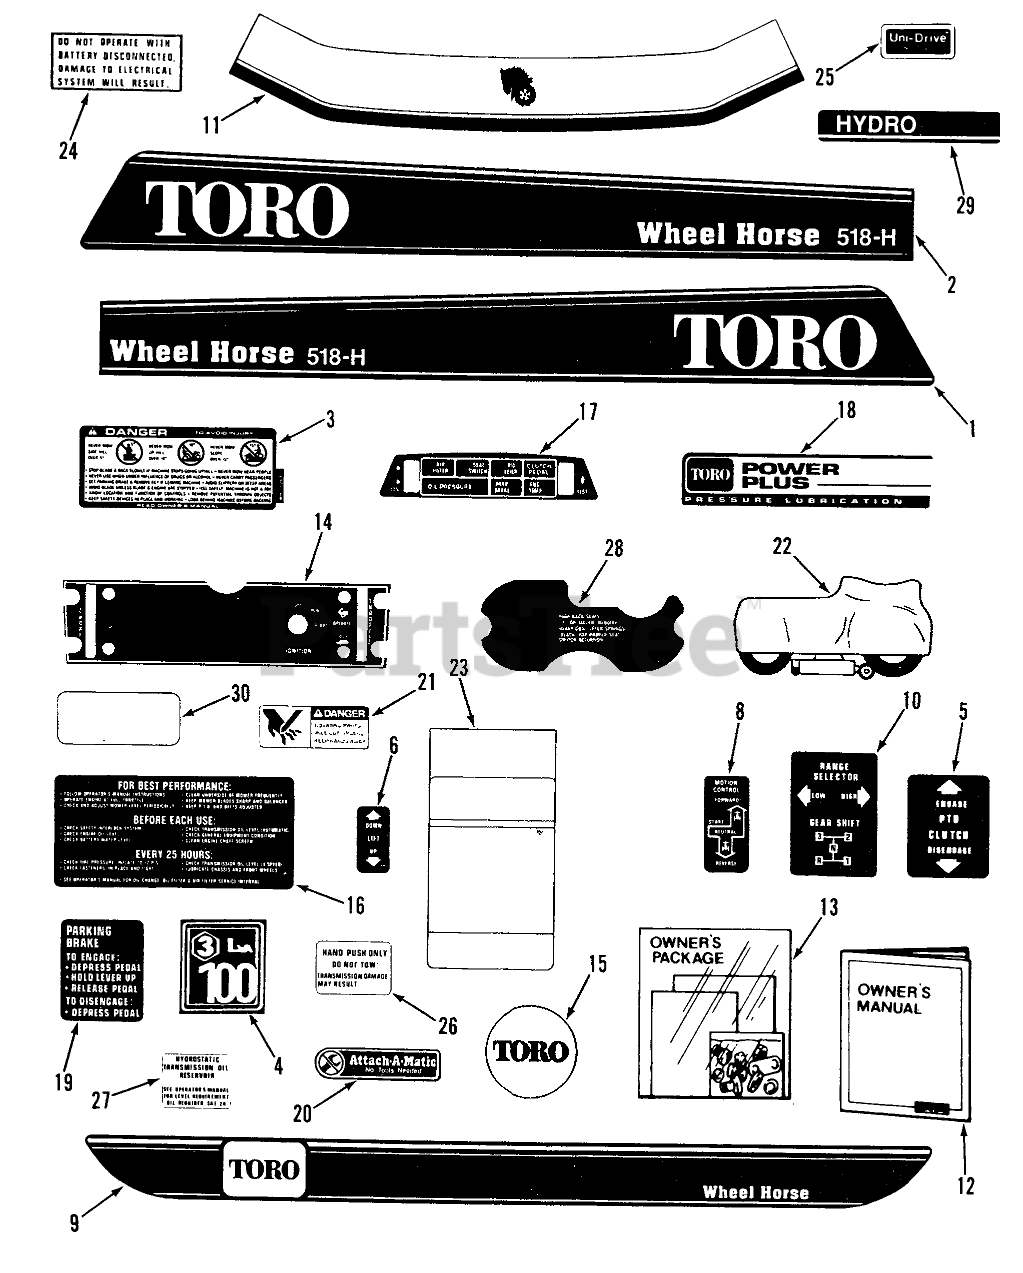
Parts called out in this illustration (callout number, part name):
1	DECAL-HOOD 518-H R H
2	DECAL-HOOD 518-H L H
3	DECAL-DANGER
4	DECAL-EUROPE
5	DECAL PTO CLUTCH
6	DECAL-LIFT
8	DECAL-MOTION CONTROL
9	DECAL-FENDER
10	DECAL-SHIFT PATTERN
11	DECAL-FRONT HOOD
12	Owner-s Manuel
13	Loose Parts Package 518-H
14	DECAL-FRONT PANEL
15	NAME-PLATE TORO LOGO
16	Decal-Rear Hood
17	DECAL-INDICATOR LTS
19	DECAL-PARKING BRAKE
20	Decal-Attac-O-Matic
21	DECAL-DANGER
22	Plastic Cover
23	MAINTENANCE-DECAL
24	DECAL ELECT SYSTEM
25	Decal-Unidrive
26	DECAL-DO NOT TOW
27	Decal-Danger
28	DECAL-SEAT LIFTER
29	DECAL-MODEL HYDRO
30	DECAL-OVERLAY
